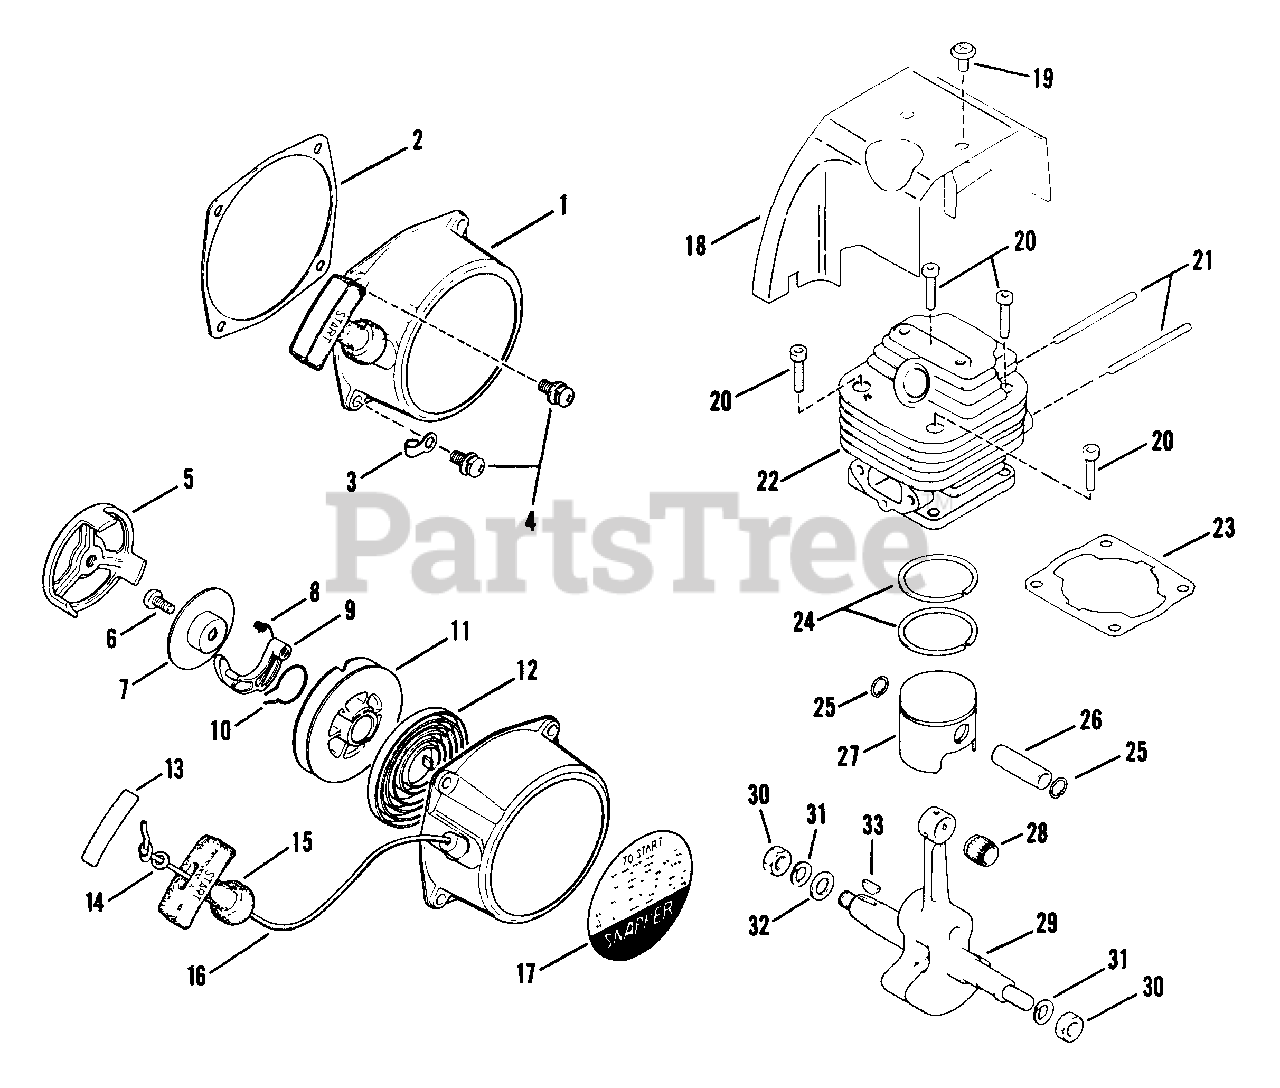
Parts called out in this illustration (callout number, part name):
1	RECOIL STARTER ASSM'Y.
2	GASKET, Recoil Starter
3	CLAMP, Fuel Tube
5	PULLEY, Recoil Starter
7	PLATE, Friction
8	SPRING, Return
9	RATCHET
10	SPRING, Friction
12	SPRING, Spiral
13	TAPE, Knob
15	KNOB, Recoil Starter
16	ROPE, Recoil Starter
17	DECAL, Starting
18	COVER, Cylinder
20	BOLT, Cylinder
21	STUD BOLT
22	CYLINDER
23	GASKET, Cylinder
24	RING, Piston
25	SNAP-RING, Piston Pin
26	PISTON
27	PIN, Piston
28	BEARING, Needle
29	CRANKSHAFT
30	NUT, Crankshaft
31	WASHER, Spring
